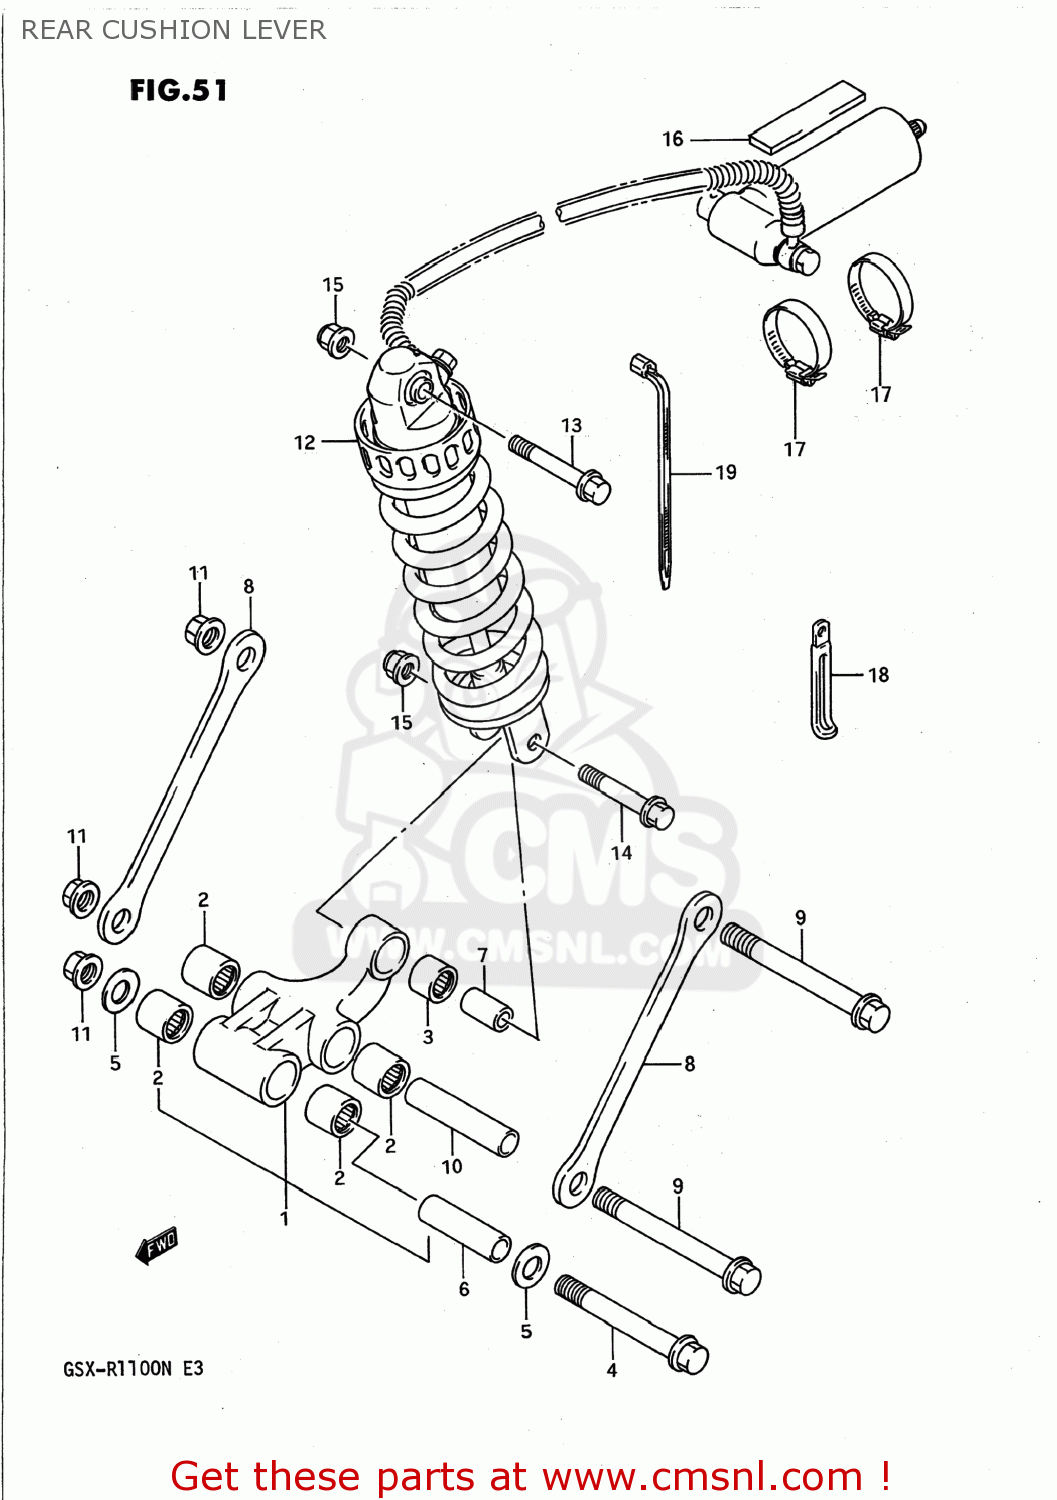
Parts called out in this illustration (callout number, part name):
1	LEVER SET,REAR CUSHION
2	BEARING(20X27X23.5)
3	BEARING(17X24X26)
4	SHAFT,RR CUSHION LEVER FR
5	WASHER
6	SPACER,RR CUSHION LEVER
7	SPACER,RR CUSHION LEVER
8	ROD,REAR CUSHION LEVER
9	SHAFT,RR CUSHION ROD
10	SPACER,RR CUSHION ROD
11	NUT
12	ABSORBER ASSEMBLY,REAR SHOCK
13	BOLT
14	BOLT(10X60)
15	NUT
16	CUSHION,RESERVOIR TANK
17	CLAMP
18	CLAMP
19	CLAMP(L:165)
